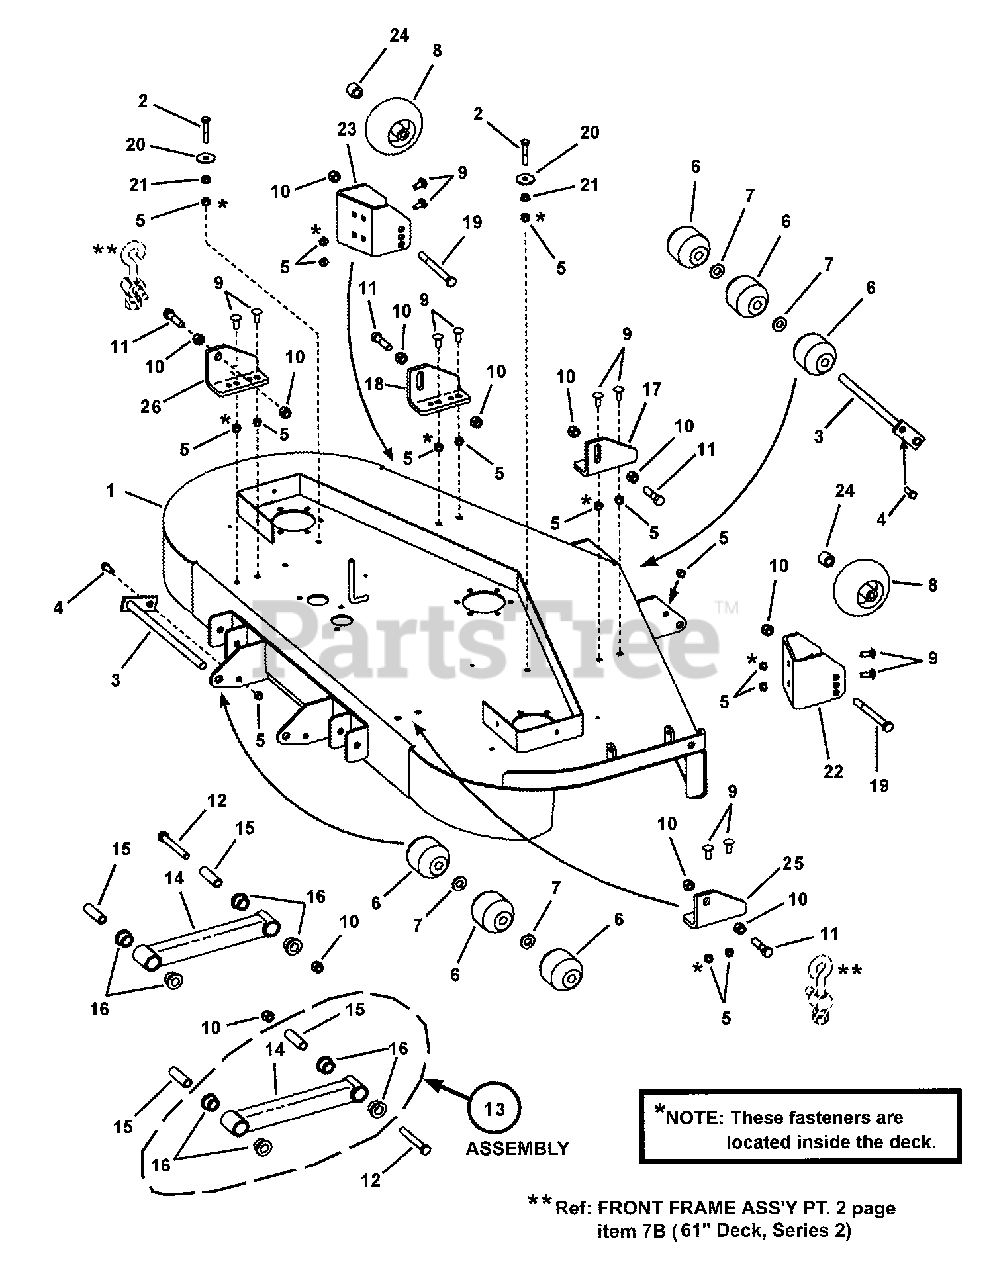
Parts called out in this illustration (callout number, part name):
1	WELDMENT, 61" Deck
2	BOLT, 3/8-16 X 2, GD5, CZ
3	WELDMENT Pivot Pin
4	BOLT, 3/8-16 X 1" GD5 CZ
5	NUT, 3/8-16 HEX NYLON LOCK
6	ROLLER, Low Density Polyethylene
7	WASHER, 5/8" Flat SAE
8	GAUGE WHEEL, Polyethylene
9	BOLT, 3/8-16 x 1" Square Neck Carriage, GR 5
10	NUT, 1/2-13 HEX NYLON LOCK
11	SCREW, 1/2-13 x 2" Hex Head Cap, GR 5
12	BOLT, 1/2-13 x 3-3/4" Hex Head Cap, GR 5
13	ASSEMBLY, Pusher Bar (Includes items 14-16)
14	WELDMENT, Pusher Bar
15	SLEEVE - Suspension
16	BUSHING - Suspension
17	BRACKET, Deck Lift, Right Hand
18	BRACKET, Deck Lift, Left Hand
19	BOLT, 1/2-13 X 5 GD5 YZ
20	WASHER, .406 x 1.50 x .120 Flat
21	NUT, 3/8-16 HEX SERRATED FLANGE
22	WHEEL BRACKET, Front Right
23	WHEEL BRACKET, Front Left
24	SPACER, Gauge Wheel
25	BRACKET, Deck Lift, RH Rear
26	BRACKET, Deck Lift, LH Rear
